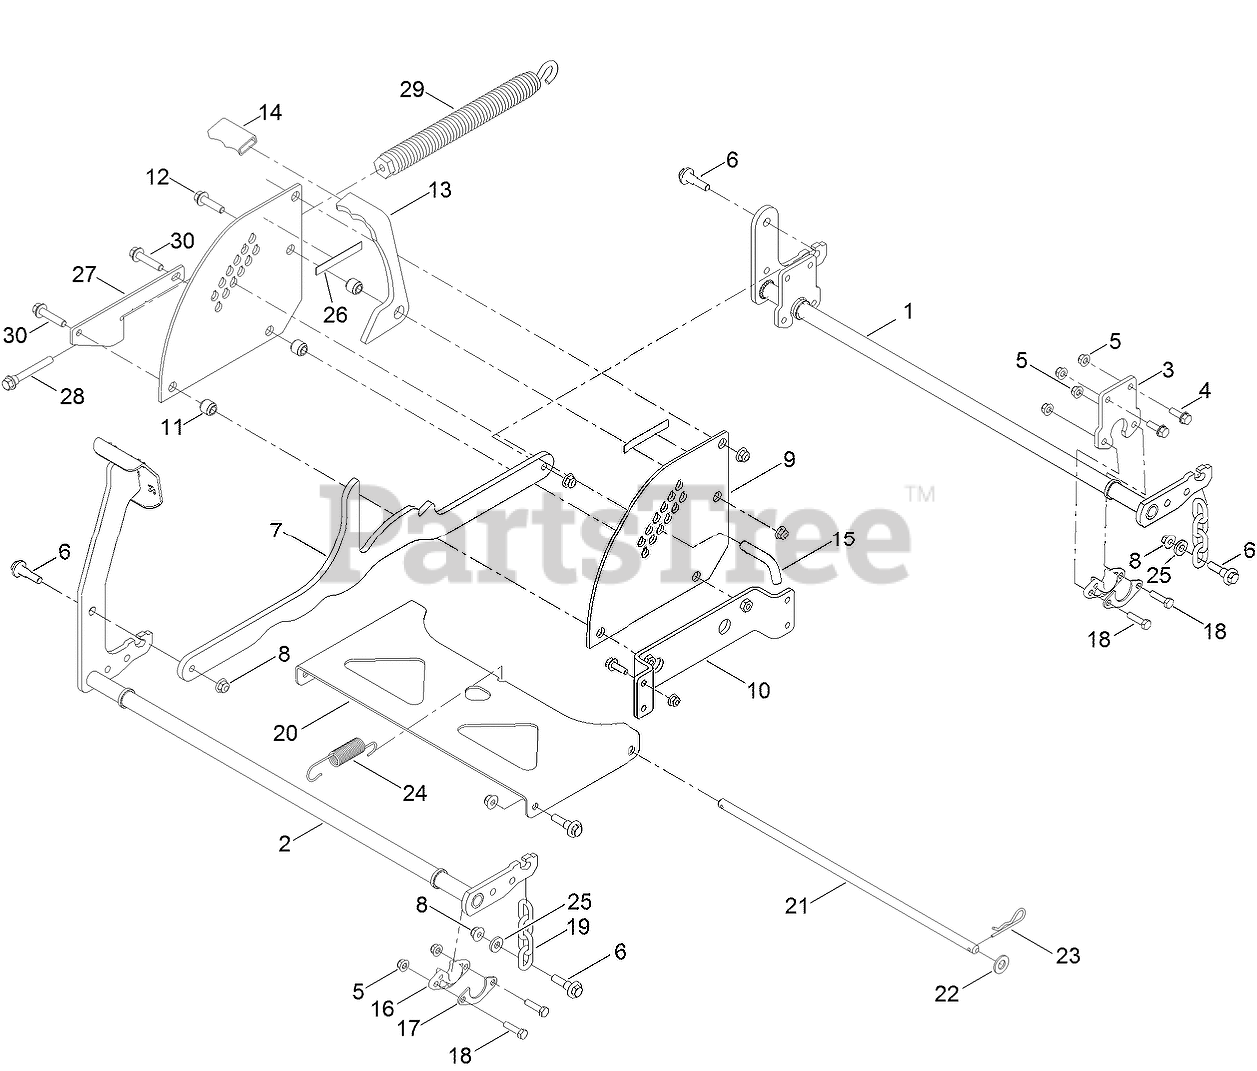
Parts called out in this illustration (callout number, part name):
1	PIVOT-REAR
2	PIVOT-FRONT
4	SCREW-HHF
5	NUT-HF, NI
6	BOLT-SHOULDER
7	LINK-HOC
8	NUT-HF, NI
9	PLATE-DECK, LIFT
10	PLATE-LIFT
11	SPACER-STEP, DOUBLE
12	SCREW-HHF
13	LOCK-TRANSPORT, HOC
14	GRIP-FLAT
15	PIN-HOC
16	BUSHING-FLANGE
17	GUSSET-LIFT, DECK
18	SCREW-HH
19	CHAIN-DECKLIFT
20	PAN-PIVOT, DECK
21	ROD-PIVOT, DECK
22	WASHER-FLAT
23	PIN-COTTER
24	SPRING-EXTENSION
25	SPACER
26	PAD-RUBBER
27	SUPPORT-SPRING
28	BOLT-SHOULDER
29	SPRING-EXTENSION
30	SCREW-HHF
